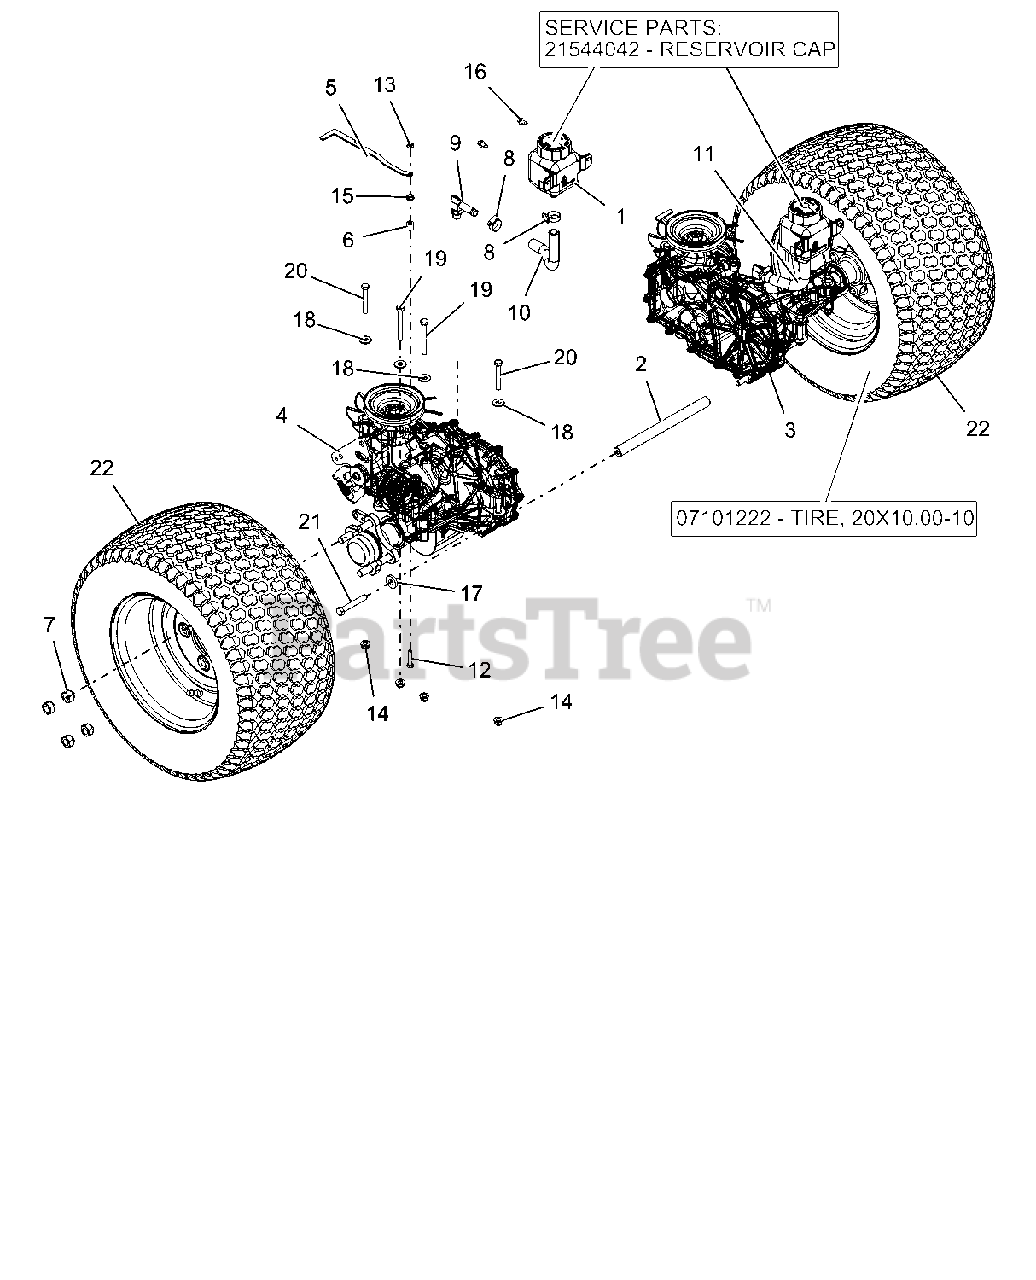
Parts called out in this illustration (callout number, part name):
1	TANK, EXPANSION
1	CAP, HYDRO RESERVOIR REPLAC.
2	ROD, TRANSAXLE BRACE (LONG)
3	TRANSAXLE,ZT2800 LH
4	TRANSAXLE,ZT2800 RH
5	BRKT, DUMP VALVE
6	BSHG-SLV .265X.500X.500
7	WHEEL NUT .500-20 YZ
8	CLAMP,.88 DIA. HOSE
9	FITTING, HYD (90 DEG)
10	HOSE, FORMED RH XL
11	HOSE, FORMED LH XL
12	@BLT-HEX .25-20X1.25 GR5 YWZC
13	NUT-LK-CTR JAM .25-20 YWZC
14	@NUT-LK-NYL-FLG .31-18 YWZC
15	@NUT-SPNLK-FLG .25-20 YWZC
16	SCR-TAP .25-20X.50 HWH TR YWZ
17	WSHR-FL-STL .406X1.00X.188 YWZ
18	@WSHR-FL-STL.38X.875X.083 YWZC
19	@BLT-HEX .31-18X2.75 GR5 YWZC
20	@BLT-HEX .31-18X2.25 GR5 YWZC
21	@BLT-HEX .38-16X2.50 GR5 YWZC
22	ASM, WHL/TIRE 20X10.00-10
22	TIRE, 20X10.00-10 (OTR)
